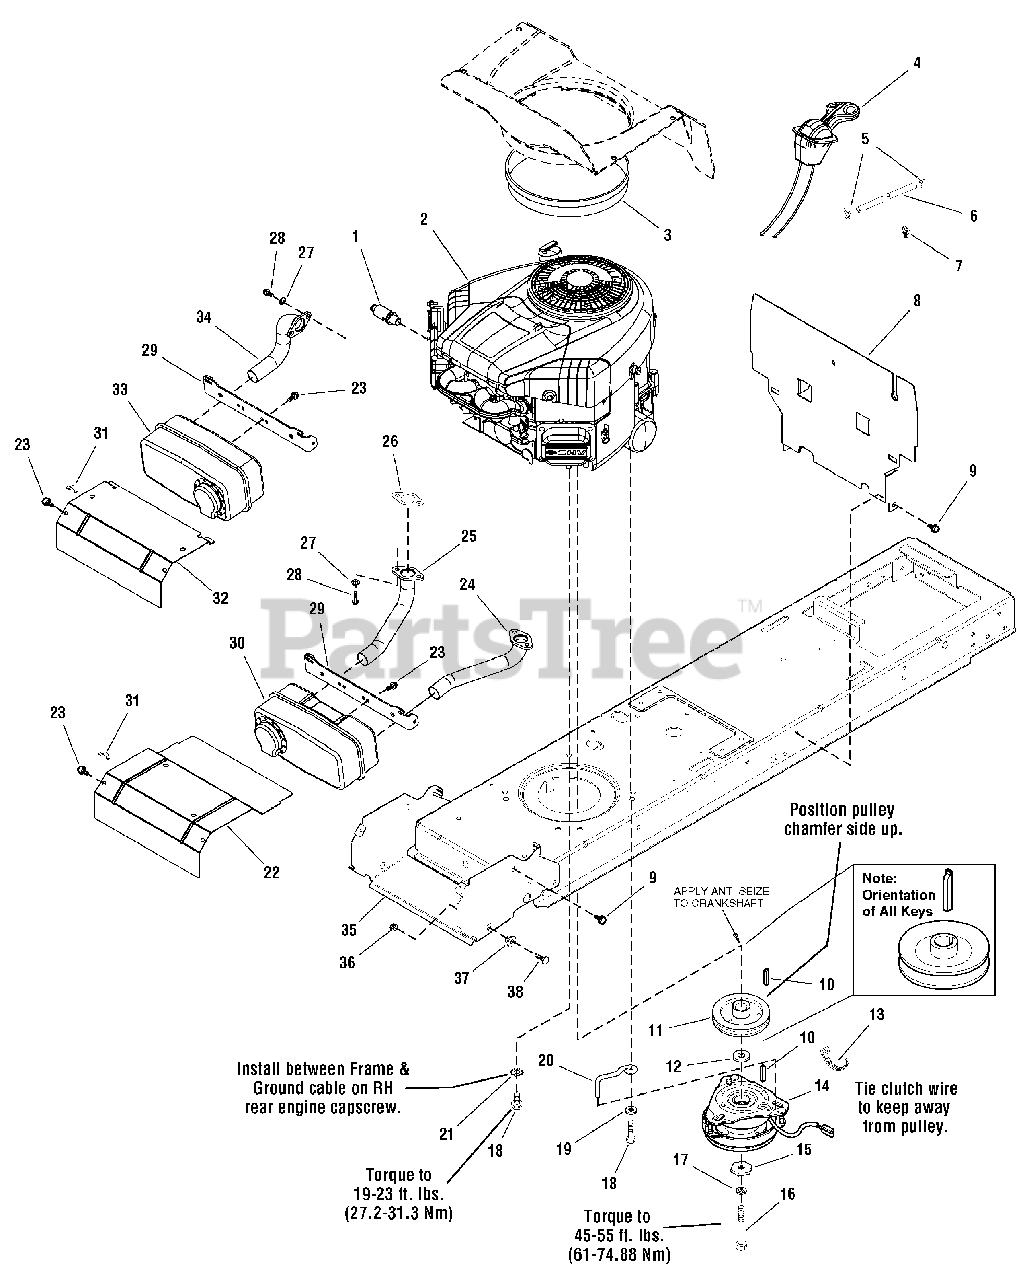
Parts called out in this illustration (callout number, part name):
1	VALVE, Oil Drain
2	ENGINE, 18HP Kohler Single Courage Pro
2	ENGINE, 20HP Briggs & Stratton Intek Twin
2	ENGINE, 22HP Briggs & Stratton Intek Twin
2	ENGINE, 24HP Briggs & Stratton Intek Twin
3	EDGING, Rubber, Short
4	CONTROL, Throttle Double 19" Long
4	CONTROL, Throttle Double 34.7" Long
5	CLAMP, Hose Type E
6	HOSE, Fuel, 45-1/2" Long
6	HOSE, Fuel 55" Long
7	CLIP, Hose, Plastic, Push-In
8	SHIELD, Heat
9	SCREW, Taptite, 5/16-18 x 5/8
10	KEY, Square, 1/4 x 1/4 x 29/32 Hard
11	PULLEY
12	SPACER, 1.01 ID x 1.68 OD x 3/8 LG Powdered Metal Yellow
13	TIE, Self Locking 7-5/16
14	CLUTCH ASSEMBLY, Mid-Range OGURA
15	WASHER
16	CAPSCREW, 7/16-20 x 3
17	LOCKWASHER, 7/16
18	SCREW, Hex, Washer Head, Taptite, 3/8-16 x 1-1/4
19	WASHER, 3/8
20	RETAINER, Clutch, Black
21	LOCKWASHER, External Tooth, 3/8
22	SHIELD, Heat B&S Twin 20GA
23	SCREW, Taptite, 1/4-20 x 1/2
24	PIPE, Exhaust w/Flange LH B&S INT
25	PIPE, Exhaust w/Flange RH B&S INT
26	GASKET, Exhaust B&S
27	LOCKWASHER, 5/16
28	CAPSCREW, Socket Head, 5/16-18 x 3/4
29	BRACKET, Muffler Mount 12GA
30	MUFFLER, B&S Twin
31	CLIP, Wire
32	SHIELD, Heat Single Cycle 20GA
33	MUFFLER, B&S Single
34	PIPE, Exhaust w/Flange Kohler
35	SUPPORT, Muffler
36	NUT, Hex Flange, 5/16-18
37	PIVOT, Hood
38	BOLT, Carriage, 5/16-18 x 1
